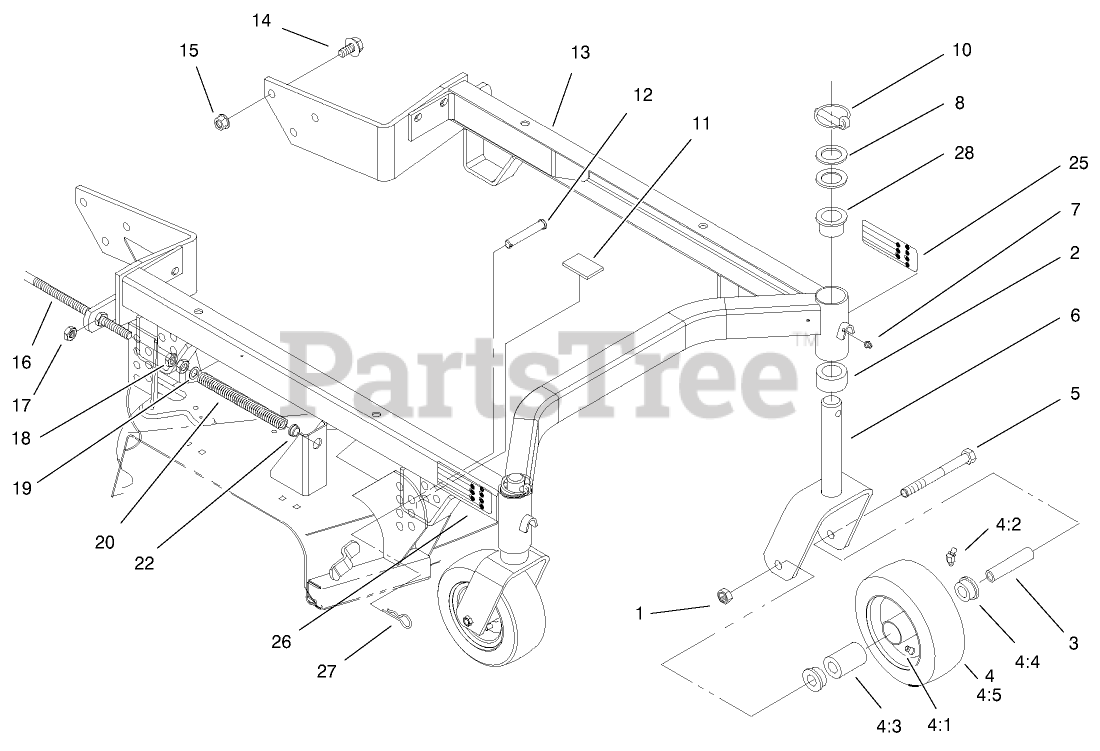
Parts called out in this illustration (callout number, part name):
1	NUT-HEX
2	SPACER-CASTOR
3	BUSHING-SPANNER
4	CASTER WHEEL ASM
4:1	STEM-VALVE
4:2	FITTING-LUBE, 45 DEG
4:3	BEARING
4:4	BEARING-OUTSIDE
4:5	TIRE-TUBELESS
5	SCREW-HH
6	CASTOR FORK ASM
7	FITTING-GREASE
8	WASHER-THRUST
10	PIN-LYNCH
11	CUSHION-RUBBER
12	PIN-CLEVIS
13	44IN CARRIER FRAME ASM
14	SCREW-HHF
15	NUT-HF
16	SHAFT-ADJUSTING
17	NUT-LOCK, NI
18	NUT-JAM
19	WASHER
20	SPRING
22	BUSHING-FLANGE
25	DECAL-HOC, LH
26	DECAL-HOC, RH
27	PIN-HAIR
28	BUSHING
